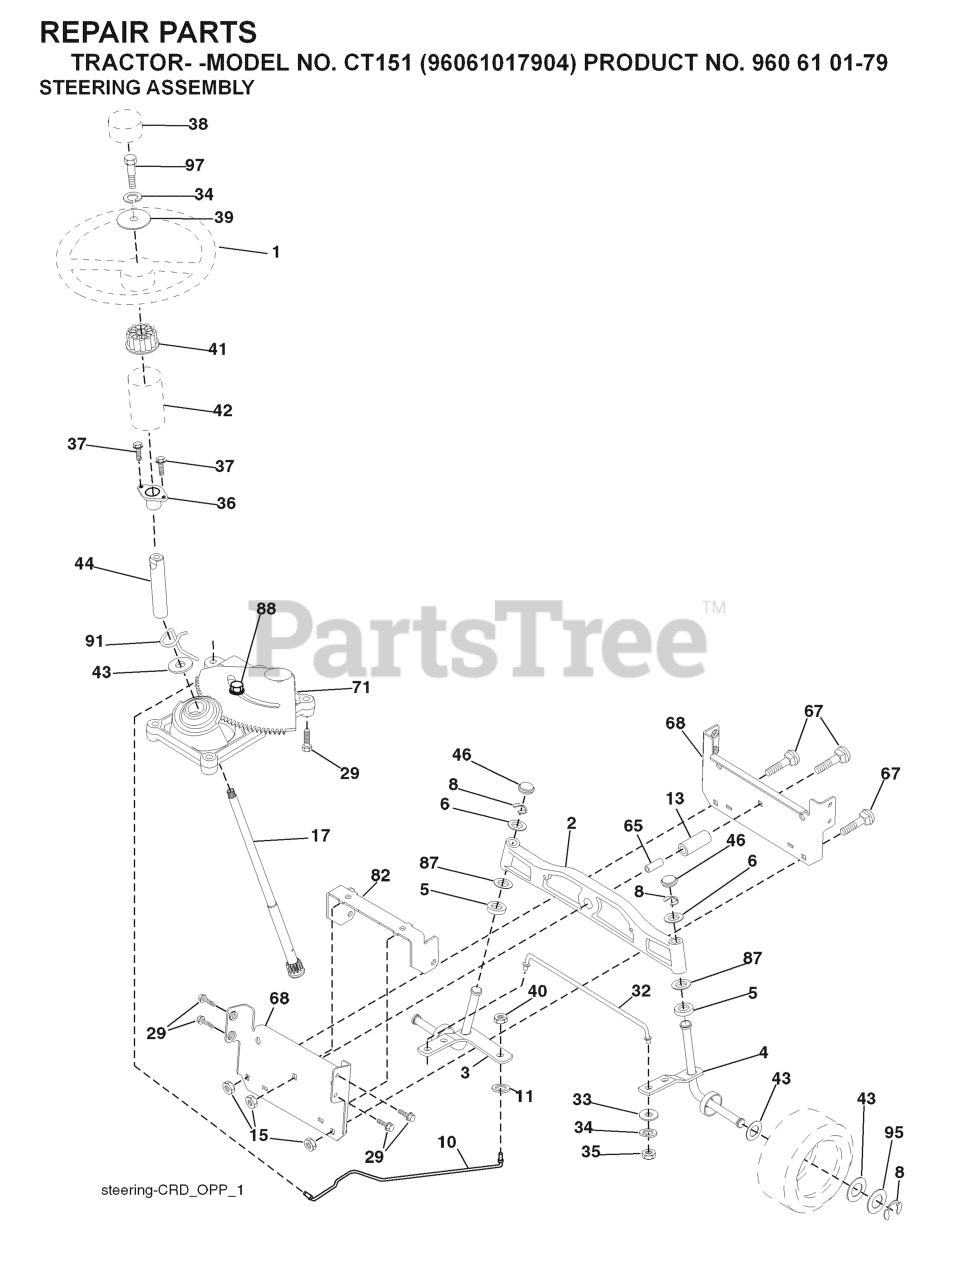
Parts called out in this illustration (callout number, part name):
1	STEERING WHEEL
2	AXLE ASSY FRONT
3	SPINDLE.ASM.LH.15"TIRES
4	SPINDLE.ASM.RH.15"TIRES
5	THRUST WASHER
10	DRAGLINK.15".TIRES.2001
11	WASHER, LOCK 3/8
13	TUBE, PIVOT AXLE
15	NUT
17	SHAFT STEERING SPLINE
29	SCREW, 3/8-16X3/4
33	WASHER M
34	WASHER.LOCK.HVY.HLCL.SPR.5/16
35	NUT, CROWNLOCK
36	BUSHING, STEERING
37	SCREW.TT.#10-32X.5.3/8.FLANGE
38	INSERT.CAP.STRG.WH.GRAY
39	WASHER.11/32
40	NUT CROWNLOCK 3/8-24
41	ADAPTER, WHEEL STNG..
42	BOOT, STEERING
44	SHAFT.EXTEN.STRG.SPLINE
46	CAP.SPINDLE.BLACK
65	SPACER BRACE AXLE
67	BOLT CARRIAGE
68	BRACE.AXLE.15"TIRES
71	STEERING ASM
82	BRACKET.SUSP.CHASSIS.FRONT.15
87	WASHER, FLAT .781 X 1 1/2"
88	BOLT, SHOULDER 7/16-20
91	CLIP.STEERING
95	WASHER.HARDENED
